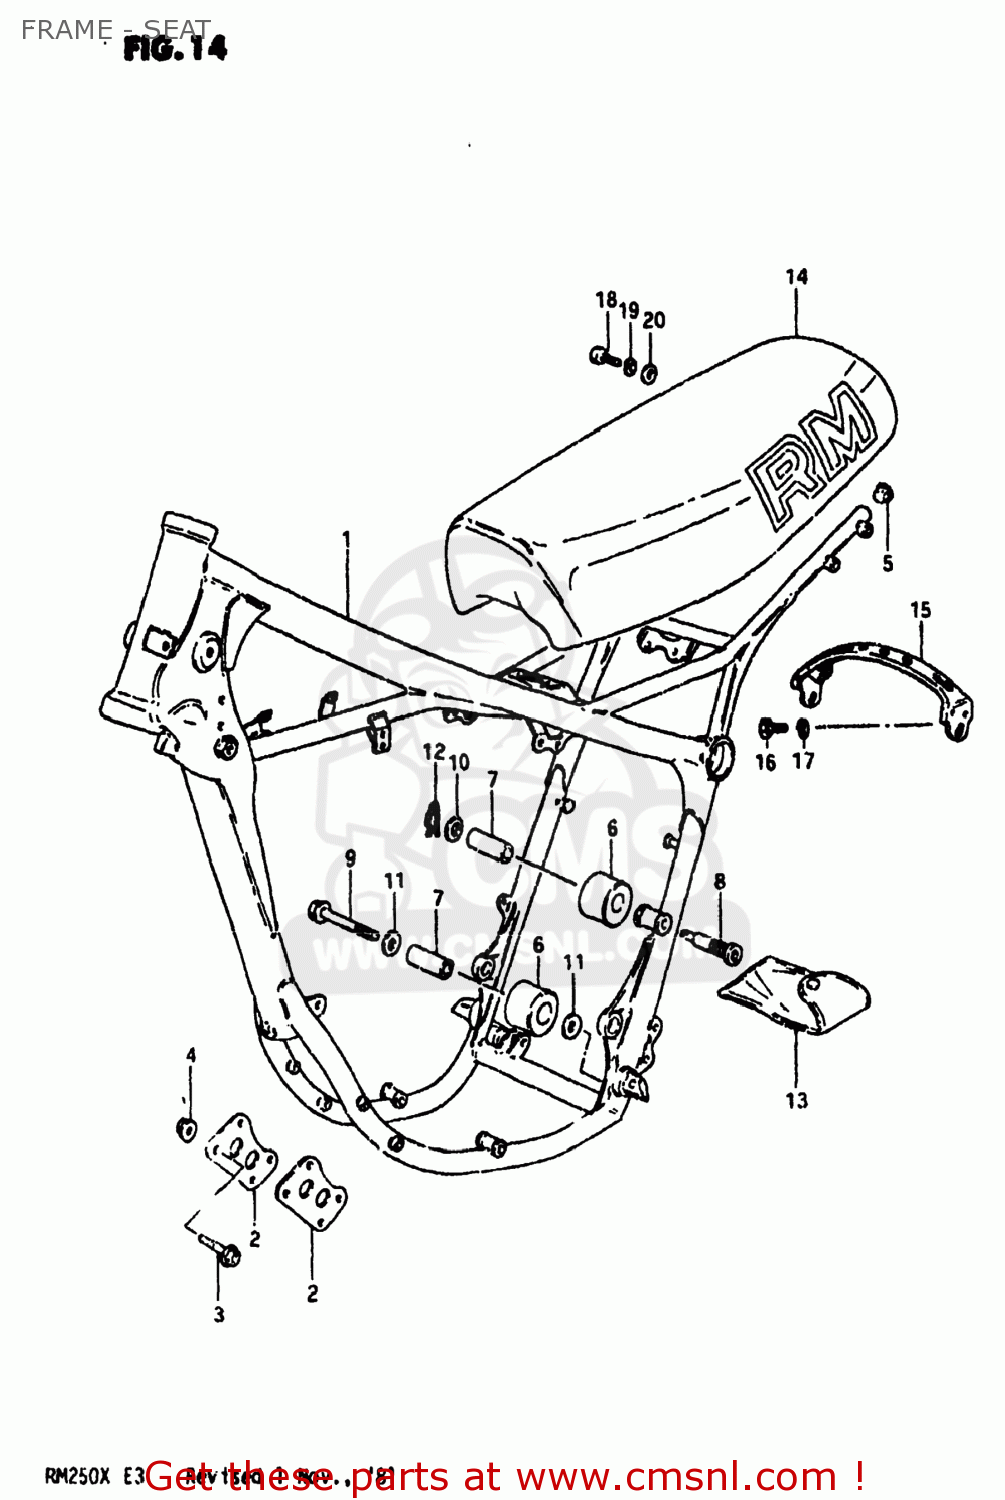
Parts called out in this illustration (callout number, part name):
1	FRAME
2	PLATE,ENGINE MOUNTING
3	BOLT
4	NUT
5	PLUG(OD:17)
6	ROLLER,CHAIN LENGTH CONTROL
7	SPACER,CHAIN LENGTH ROLLER
8	BOLT,CHAIN LENGTH ROLLER
9	BOLT(8X45)
10	WASHER
11	WASHER
12	CLIP
13	TOOL SET
14	SEAT ASSEMBLY
15	PLATE SEAT REAR STAY
16	BOLT, UPPER
17	LOCK WASHER
18	BOLT
19	LOCK WASHER
20	WASHER (8.2X20X1.6)
